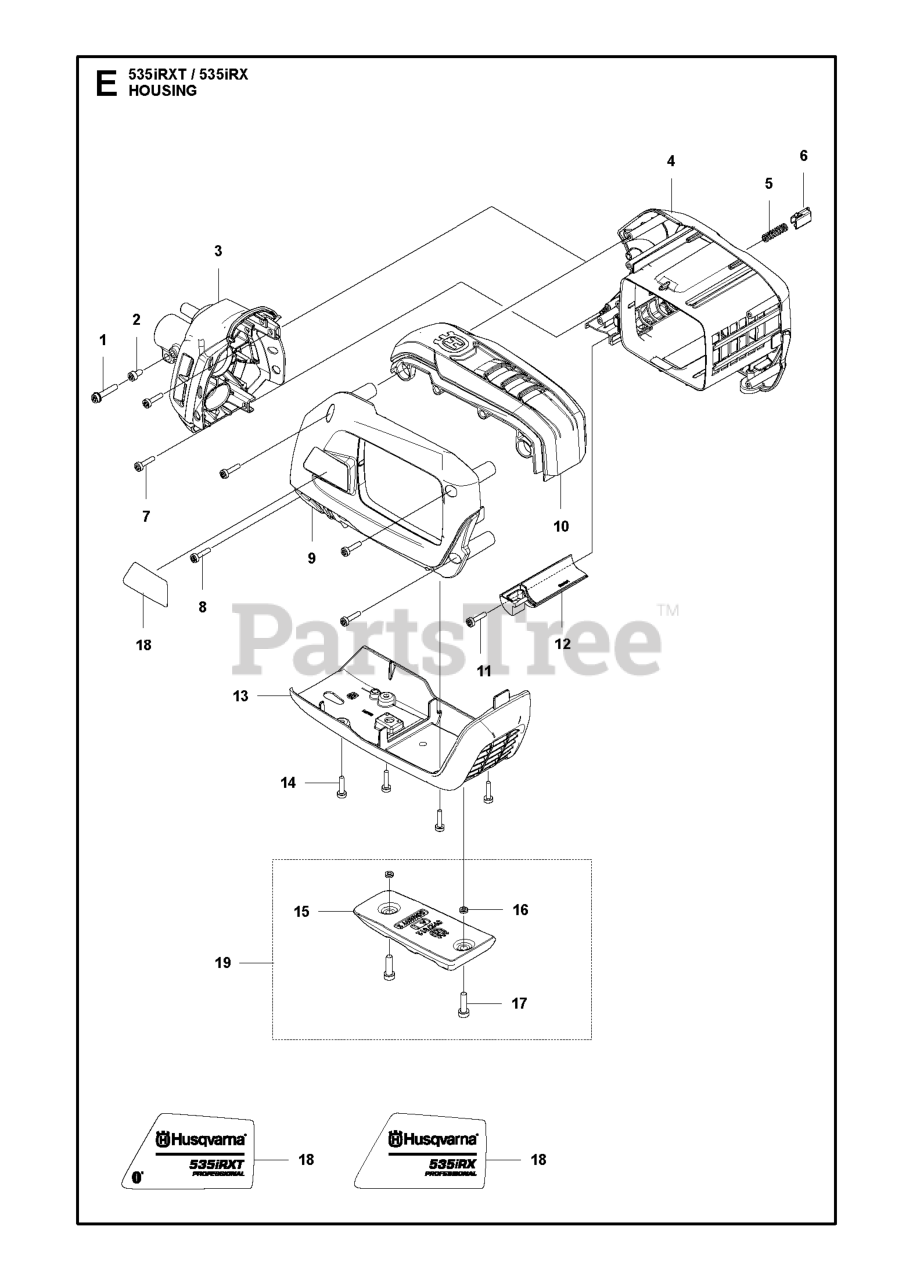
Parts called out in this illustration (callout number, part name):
5	SPRING PUSH OUT
6	PUSH BUTTON
7	SCREW ITXSCT PW4.2X18 10.9 ZN
8	SCREW ITXSCT PW4.2X18 10.9 ZN
11	SCREW ITXSCT PW4.2X18 10.9 ZN
12	AIR CONDUCTORS
13	SKID PLATES
14	SCREW ITXSCT PW4.2X18 10.9 ZN
16	LOCKING NUT M6
17	SCREW ITXSCM
18	DECALS
